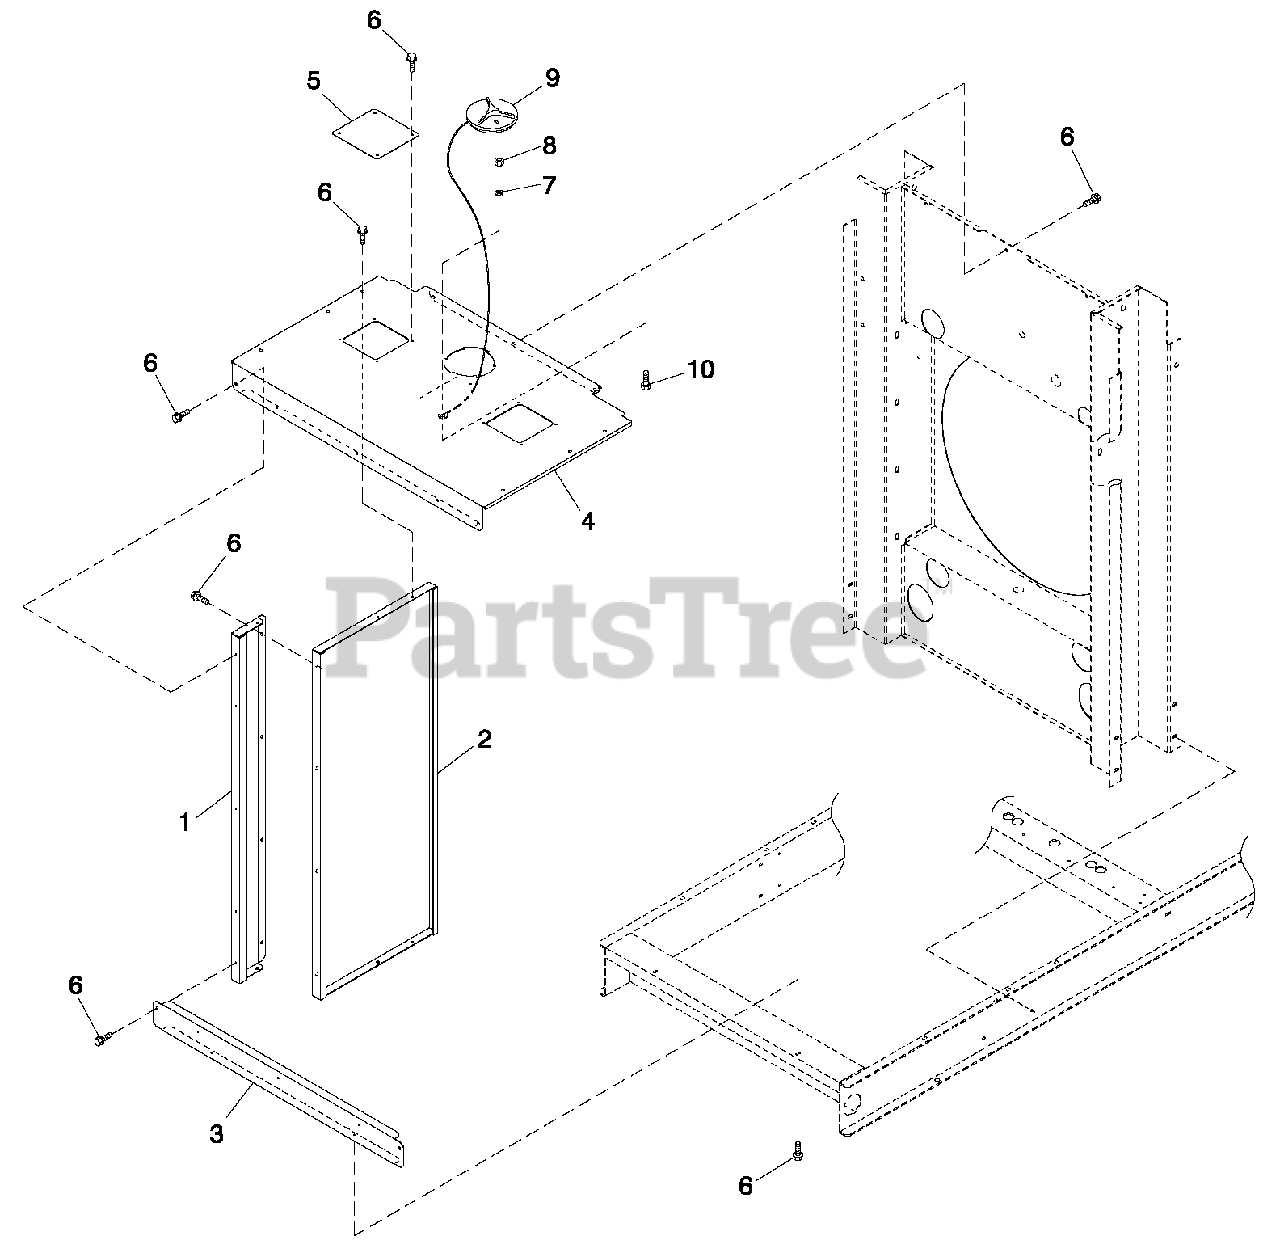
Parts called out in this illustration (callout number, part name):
1	PANEL C3 FRONT SIDES
2	PANEL C3 REAR SIDES
3	PANEL LOWER FRONT
4	PANEL C3 TOP
5	ACCESS COVER 160 X 170 GALV
6	SCREW THF M6-1 X 16 N WA Z/JS
7	WASHER LOCK M6-1/4
8	NUT HEX M6 X 1.0 G8 YEL CHR
9	ASSY ACCESS COVER
10	SCREW HHC M6-1.0X 16 G8.8
